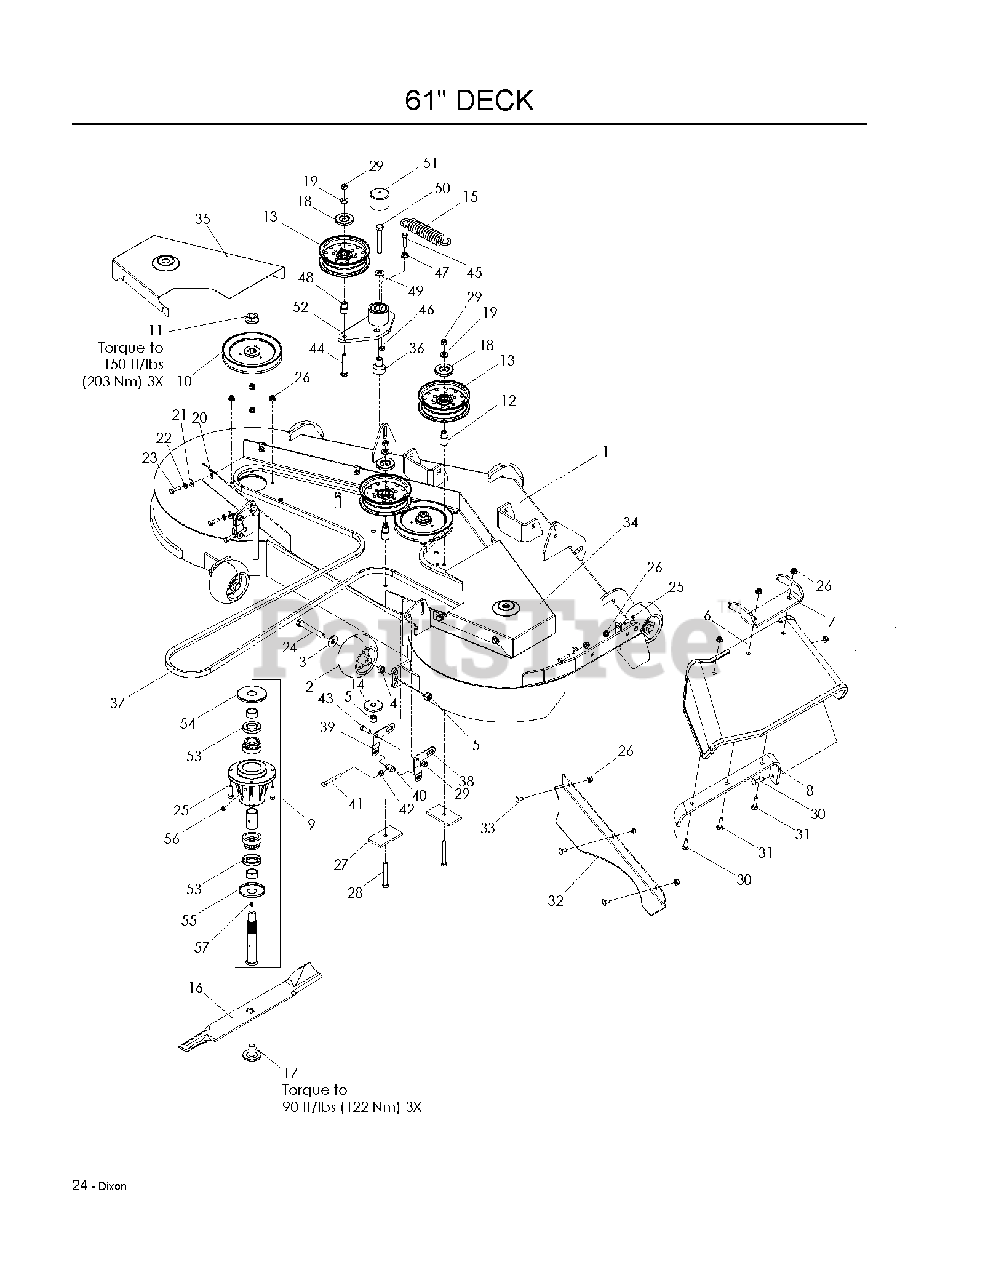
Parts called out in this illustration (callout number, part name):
1	DECK W/DECALS 61" DIX
2	GAUGE WHEEL
3	WASH USS FLAT 1/2
4	NUT 1/2 HEX JAM
5	NUT 1/2-13 HEX NYLOC ZD
6	CHUTE, RUBBER DISCHARGE 52/61"
7	PIVOT BRACKET - CHUTE
8	BRKT, REINF - CHUTE 52/61"
9	HOUSING ASM, 52/61
10	PULLEY, 61
11	NUT FLANGE 3/4-16
12	IDLER BUSHING
13	IDLER PULLEY
14	WASHER, SUPPORT
16	BLADE, 21"
17	BLADE BOLT/WASHER
18	DUST SHIELD
19	WASHER, 3/8 THICK
20	U-CLIP 5/16-18 NUT RETAINER
21	WASHER 5/16 FLAT
22	WASHER 5/16 LOCK
23	HCS 5/16C X 1
24	HCS 1/2-13 X 4 GR 5 ZD
25	HCS 5/16C X 1 1/4
26	SUPPORT PLATE
27	5/16-18 NYLOC FLANGE NUT
28	HCS 3/8C X 3
29	NUT 3/8-16 NYLOC
30	BOLT, CARRIAGE 5/16X1-1/4
31	RHSNB 5/16-18 X 1-1/2 GR 5 ZD
32	CONFINEMENT PLATE 61
33	CARRIAGE BOLT 5/16C X 5/8"
34	SHIELD, BELT 61 RT, BLUE
35	SHIELD, BELT, 61 LT, BLUE
36	PIVOT, BEARING
37	BELT, DECK - ESTATE
38	PITCH, ADJUST, RT
39	PITCH, ADJUST, LT
40	TRUNION, PITCH
41	5/16-18X3HHBG5 ALTHD
42	NUT 5/16C HEX
43	HCS 3/8C X 1
44	RHSNB 3/8-16 X 2.75
45	HCS 3/8-16 X 1-1/2
46	NUT 3/8-16 HEX JAM
47	NUT 3/8C WHIZ
48	BUSHING, IDLER
49	CONTACT BELLSPR 1/2
50	HCS 1/2C X 3 1/4
51	CAP, VINYL
52	ARM-IDLER W/BRG
53	SHAFT SEAL
54	TOP DUST CAP
55	BOTTOM DUST CAP
56	PLUG-VENTED
